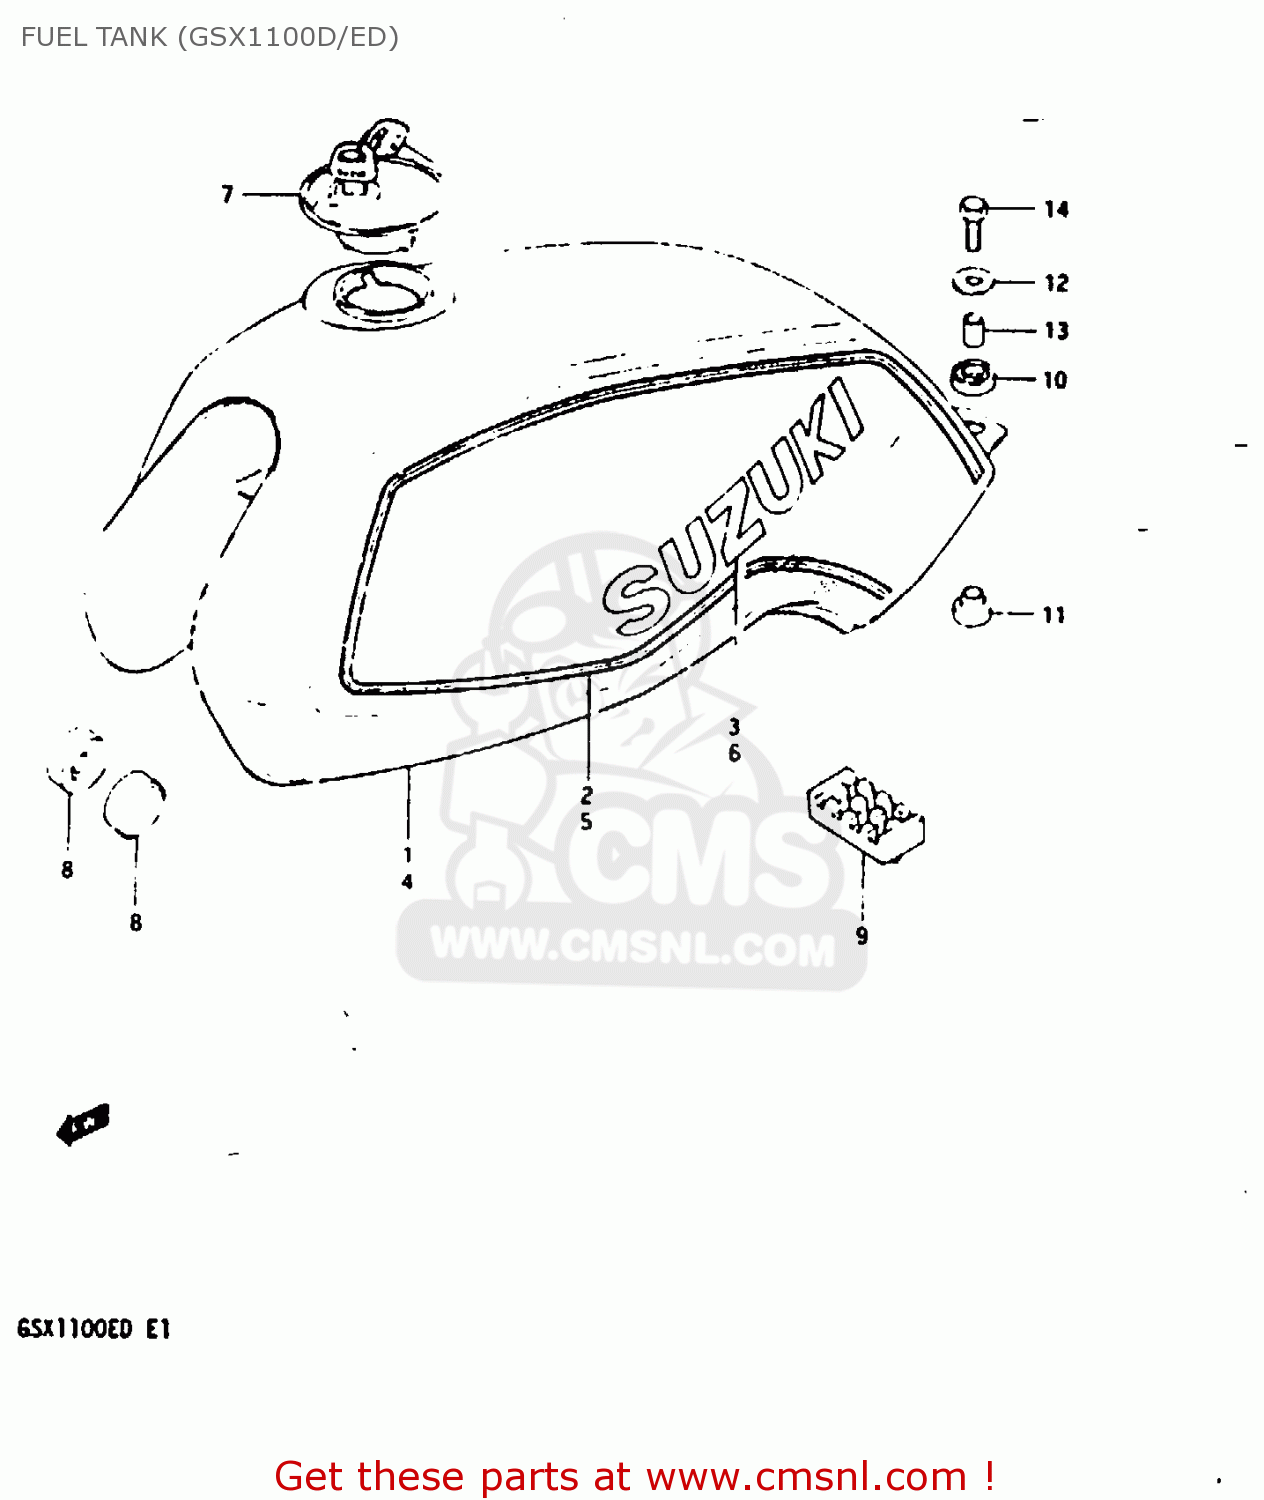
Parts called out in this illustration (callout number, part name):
1	TANK, FUEL
2	TAPE SET, FUEL TANK
3	EMBLEM(SILVER)
4	TANK ASSY, FUEL
5	TAPE SET, FUEL TANK
6	EMBLEM(SILVER)
7	CAP SET,FUEL TANK
8	CUSHION
9	CUSHION,FUEL TANK CTR
10	CUSHION
11	CUSHION
12	WASHER (6.5X24X1.6)
13	SPACER
14	BOLT
